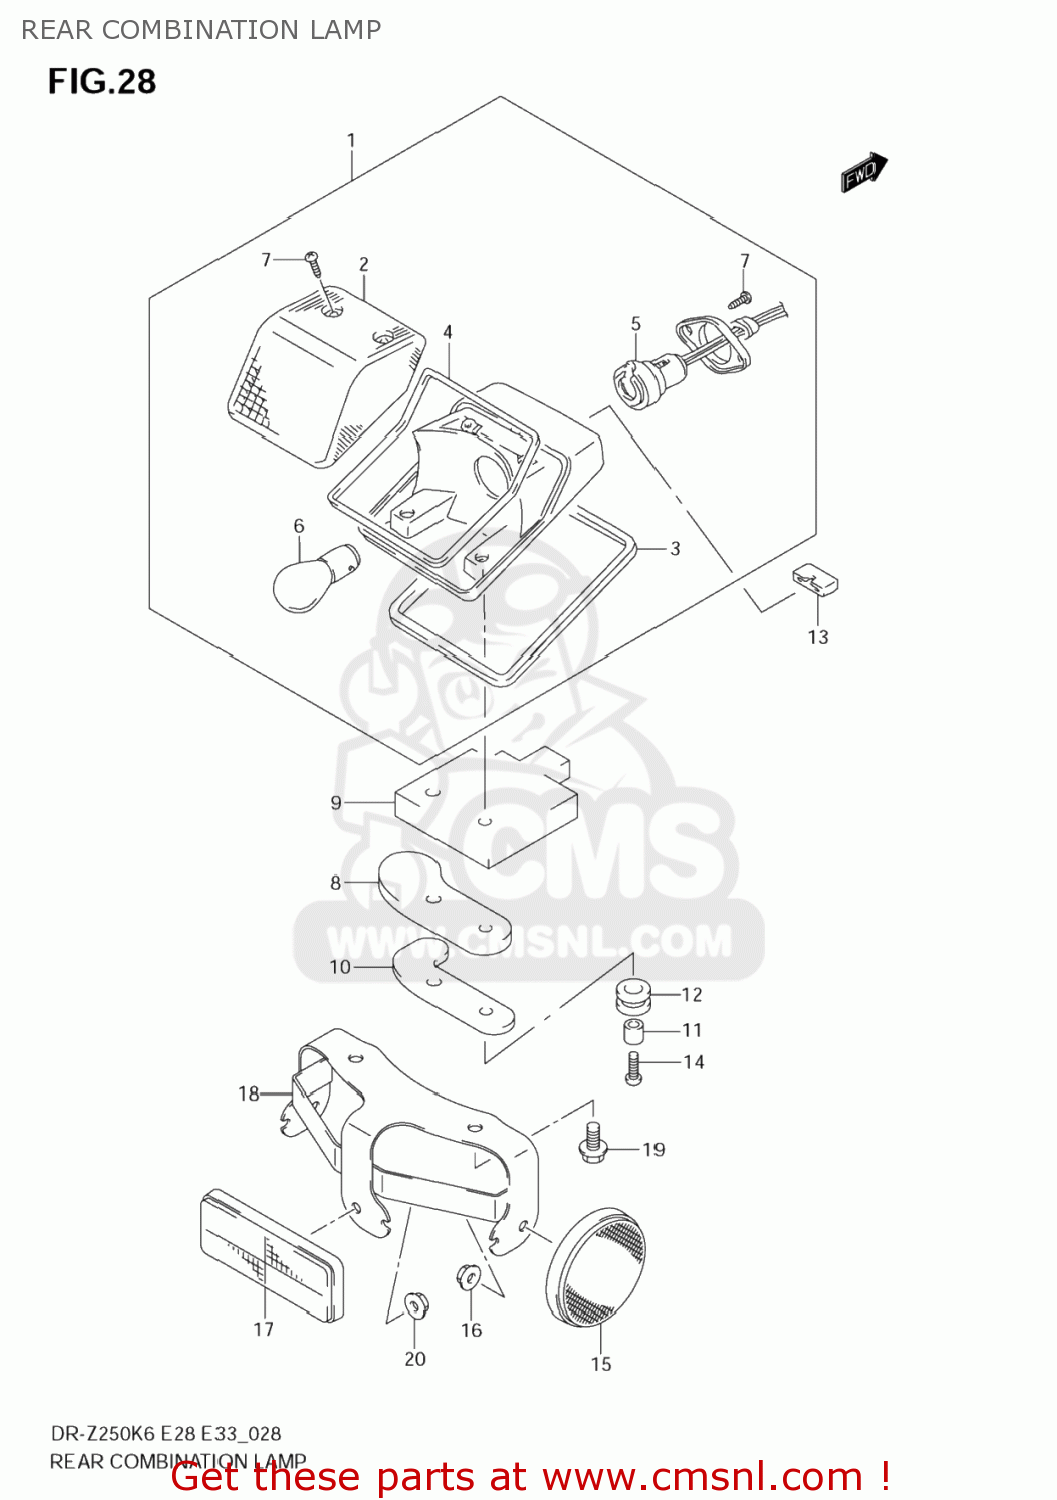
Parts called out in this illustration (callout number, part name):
1	LAMP ASSY, REAR COMB
2	LENS
3	GASKET
4	GASKET
5	SOCKET & CORD
6	BULB(12V21/5W)
7	SCREW
8	CUSHION,BRACKET
9	CUSHION,LWR
10	BRACKET,RR COMBI LAMP LWR
11	SPACER(6.5X9X12.5)
12	CUSHION
13	CUSHION
14	SCREW
15	REFLEX REFLECTOR,RR
16	NUT
17	REFLECTOR ASSEMBLY,REAR
18	BRACKET,SIDE & RR RR
19	BOLT
20	NUT
